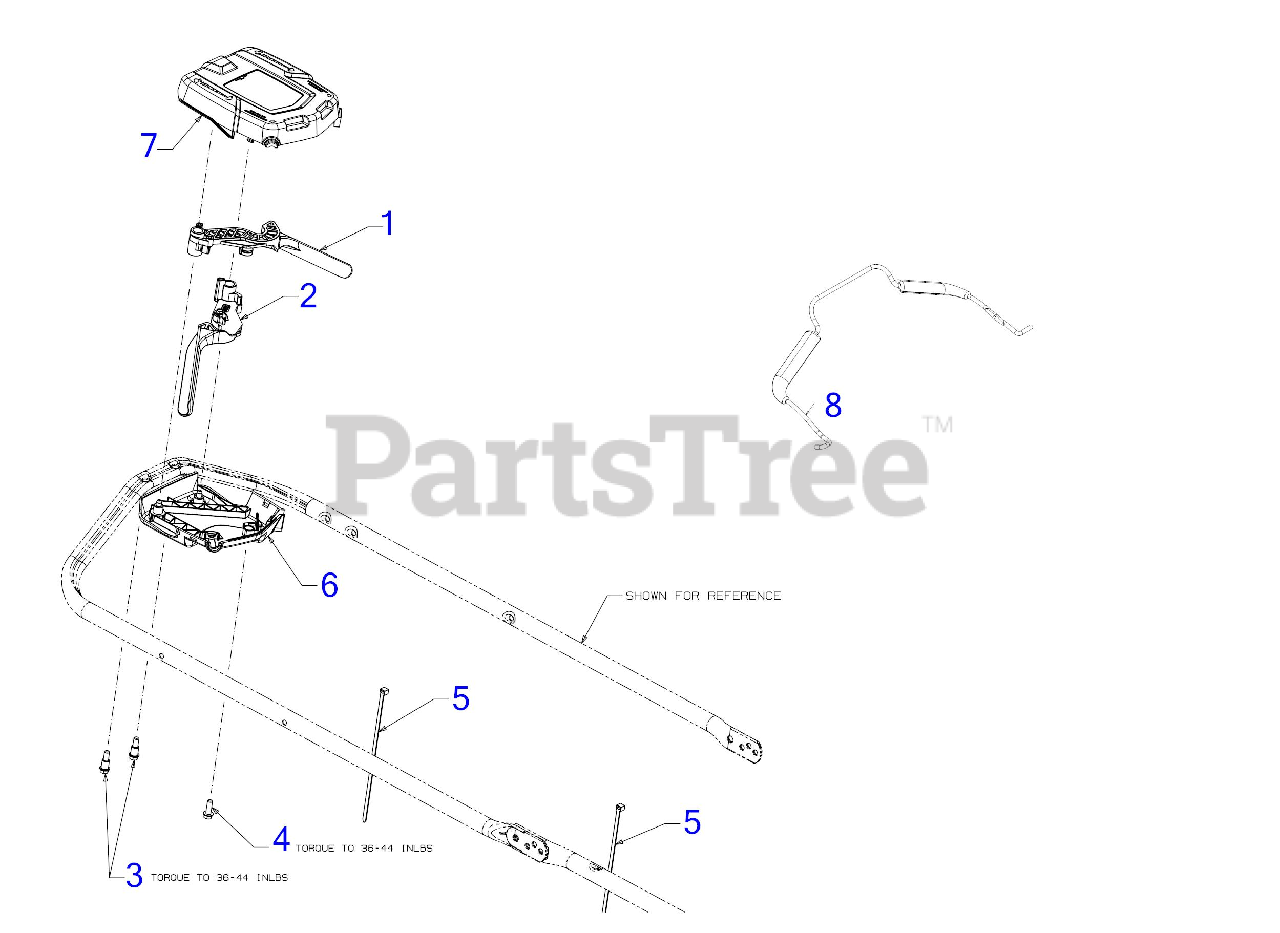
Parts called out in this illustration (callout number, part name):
1	CONTROL LEVER LH
2	CONTROL LEVER RH
3	SHOULDER SCREW 1/4-15 x .970
4	SCREW 1/4-15 x .750
5	7" CABLE TIE
6	LOWER CONTROL HOUSING
7	UPPER CONTROL HOUSING
8	BAIL ASSEMBLY
